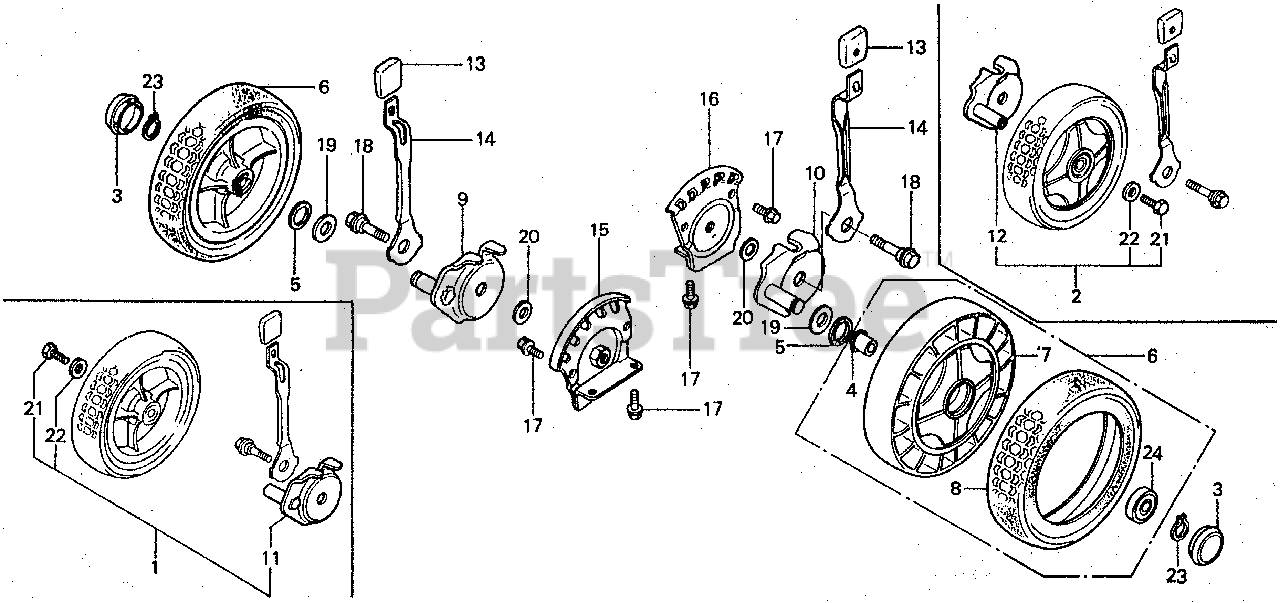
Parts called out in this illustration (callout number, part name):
1	ARM, R. KIT ADJUSTER
2	ARM KIT, L. ADJUSTER (N/A: SEE COMPONENTS)
3	CAP, WHEEL
4	BUSH, WHEEL
5	FELT, WHEEL SHAFT
6	WHEEL ASSY., RR. *NH31* (MCKINLEY WHITE)
7	HUB, RR. WHEEL *NH31* (MCKINLEY WHITE)
8	TIRE, RR. (8INCH)
9	ARM, R. KIT ADJUSTER
10	ARM, L. FR. ADJUSTER
11	ARM, R. RR. ADJUSTING
12	ARM, L. RR. ADJUSTING
13	GRIP, ADJUSTER
14	PLATE, RR. ADJUSTING (NOT AVAILABLE)
15	PANEL, R. RR. ADJUSTING
16	PANEL, L. RR. ADJUSTING (NOT AVAILABLE)
17	BOLT, FLANGE (6X12) (CT200)
18	BOLT, RR. ADJUSTING ARM
19	WASHER (15MM)
20	WASHER (10MM)
21	BOLT, HEX. (8X12)
22	WASHER, PLAIN (8MM)
23	CIRCLIP (OUTER) (15MM)
24	BEARING, RADIAL BALL (6202)
